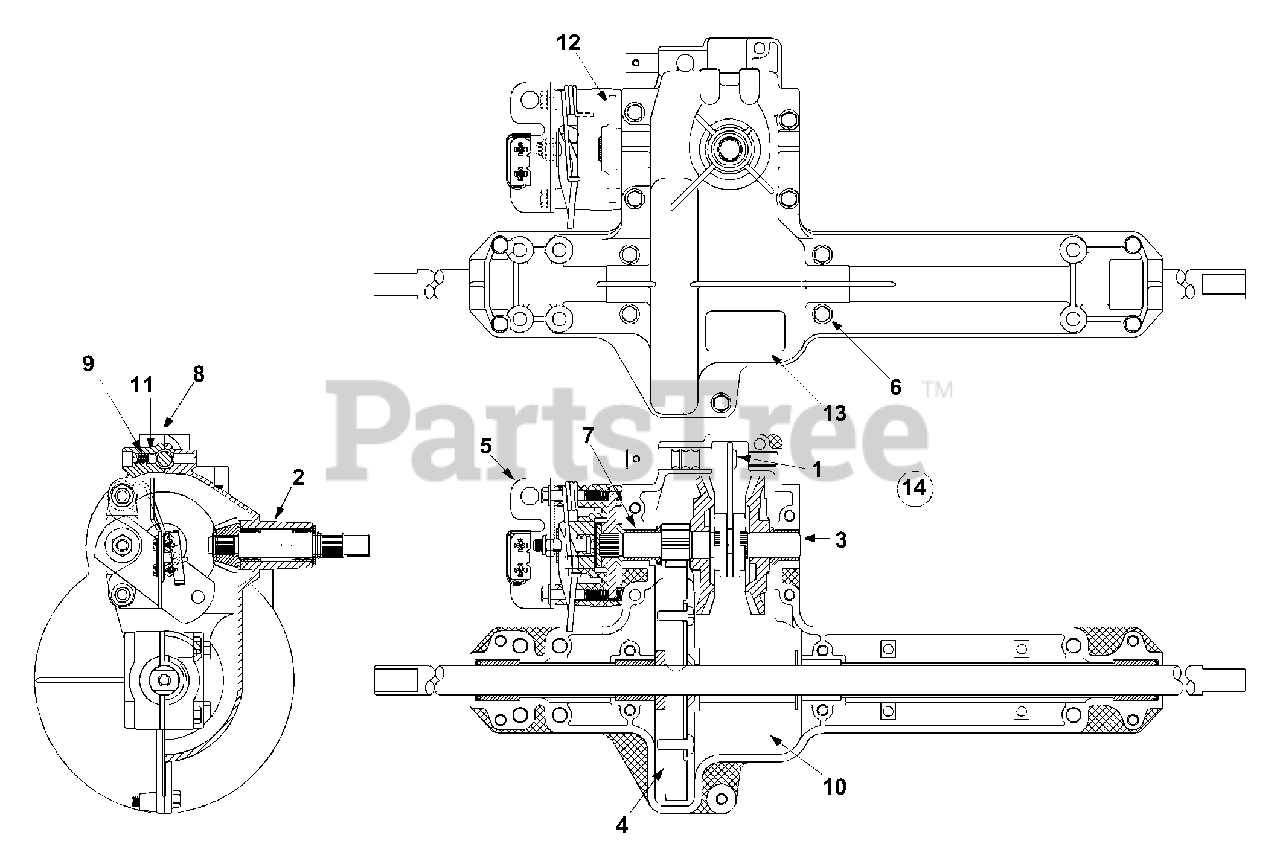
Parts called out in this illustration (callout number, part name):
1	Shaft Assembly: Detent
2	Upper Housing Assembly
3	Drive Shaft Assembly: LH Brake
4	Axle Assembly
5	Brake Assembly: Yoke LH
6	TT Screw 1/4-20 x 1.625"
7	Brake Pad
8	Lower Housing
9	Spring Detent
10	Grease
11	Ball: Detent: .250
12	Brake Disc
14	Transmission Assembly Complete
